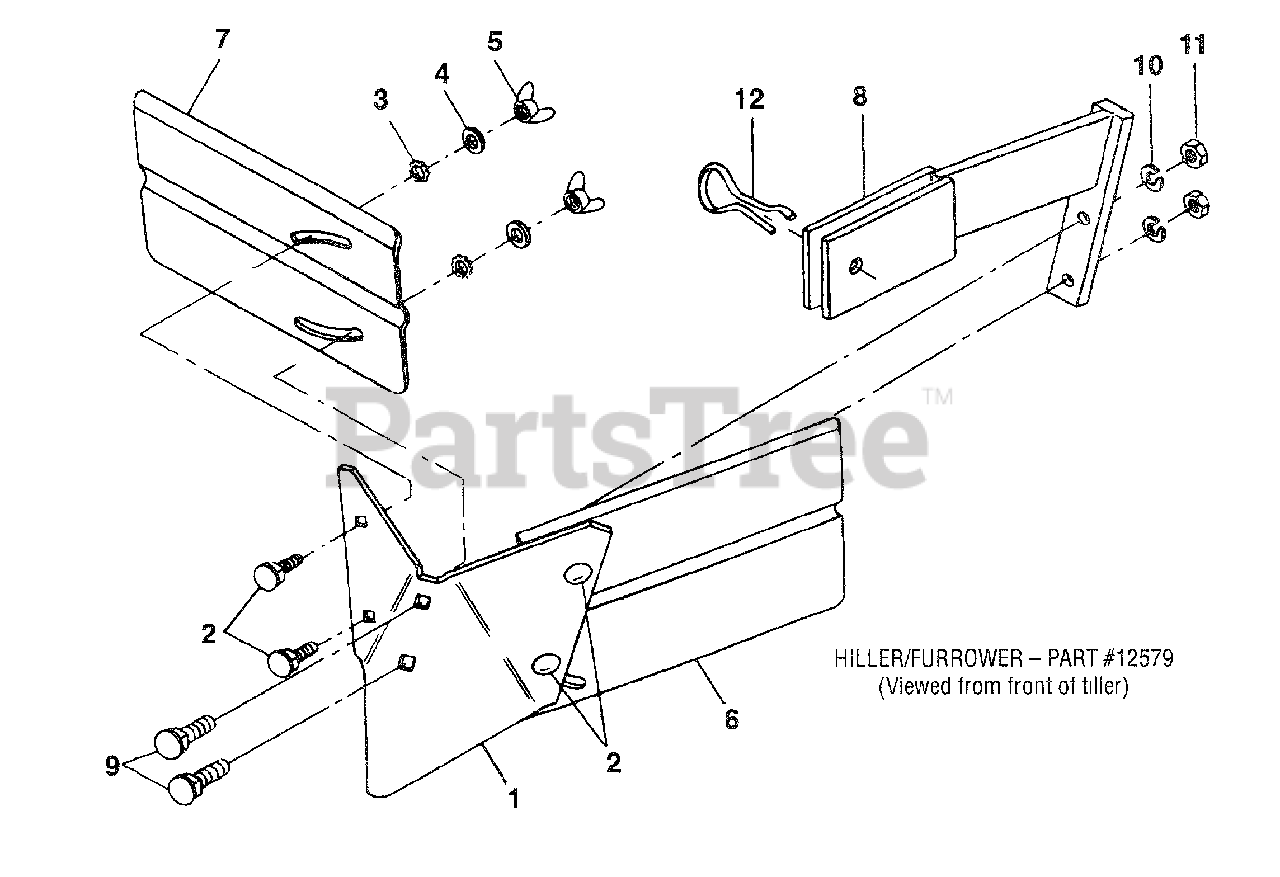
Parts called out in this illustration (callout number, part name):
1	Furrower-blade only
2	Carriage Bolt-5/16-18 x 3/4
3	Star Washer-external tooth, 5/16
4	Plain Washer-5/16 S.A.E
5	Wing Nut-5/16-18
6	Hiller Wing-left
7	Hiller Wing-right
8	Bracket-blade mounting
9	Carriage Bolt-blade mounting, 3/8-16 x 1-1 /2
10	Lockwasher-3/8, plated
11	Nut hex, 3/8-16, plated
12	Pin-clinch
12579	Hiller/Furrower-
